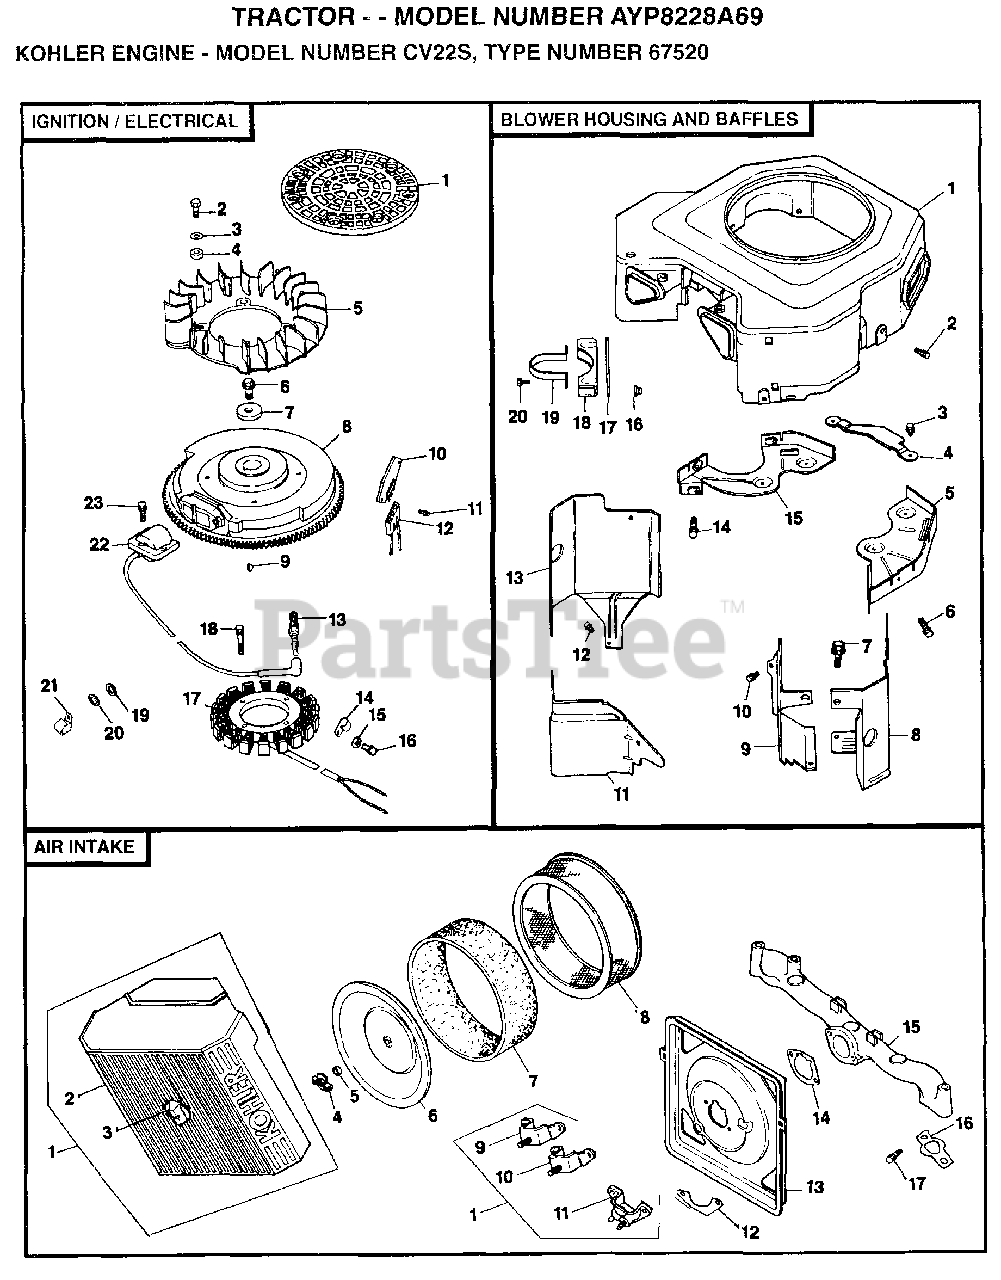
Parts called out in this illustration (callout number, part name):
1	SCREEN, GRASS
1	KIT, AIR CLEANER COVER
2	SCREW
2	COVER, AIR CLEANER
3	WASHER
3	SCREW
6	SCREW
7	SCREW
8	FLYWHEEL ASSEMBLY
9	KEY
10	RECTIFIER-REGULATOR
10	SCREW, MOUNTING
12	CONNECTOR
12	SCREW
14	SCREW
18	SCREW
18	BRACKET, BREATHER SEPARATOR
19	WASHER, PLAIN 1/4
19	STRAP, BREATHER SEPARATOR
20	WASHER
21	CLIP
23	SCREW
